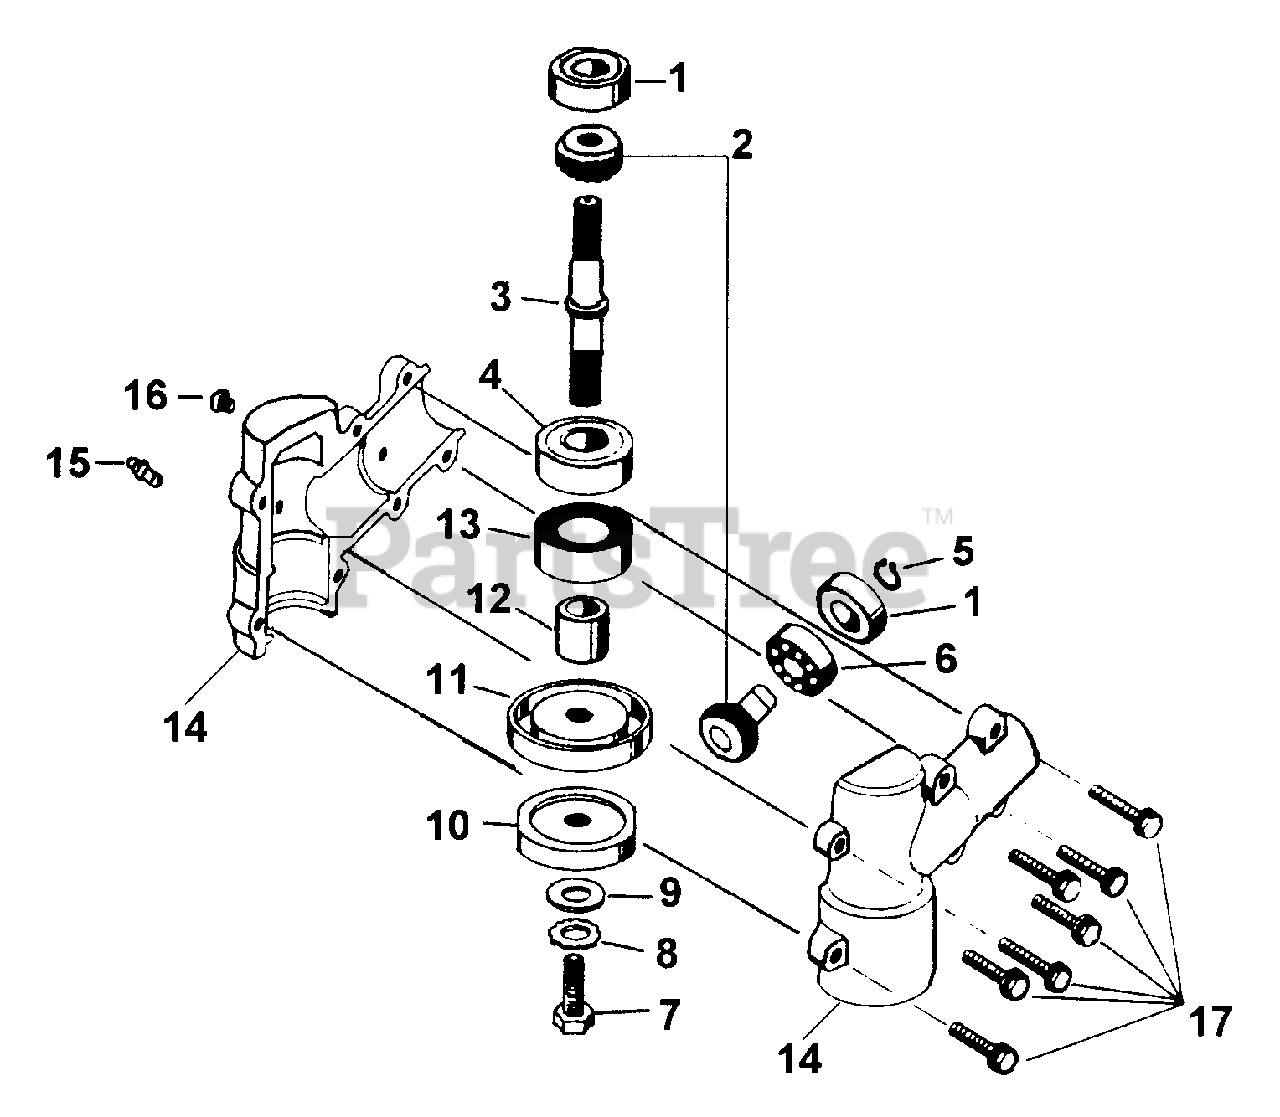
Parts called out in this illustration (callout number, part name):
1	Bearing
2	Gear Set Kit
3	Shaft, Gear
4	Bearing
5	Snap Ring
6	Bearing
7	Bolt
8	Washer
10	Flange Washer
11	Flange Washer
13	Bearing
14	Housing Set
15	Grease Fitting
16	Screw, Self Tapping
17	Screw, Self Tapping
